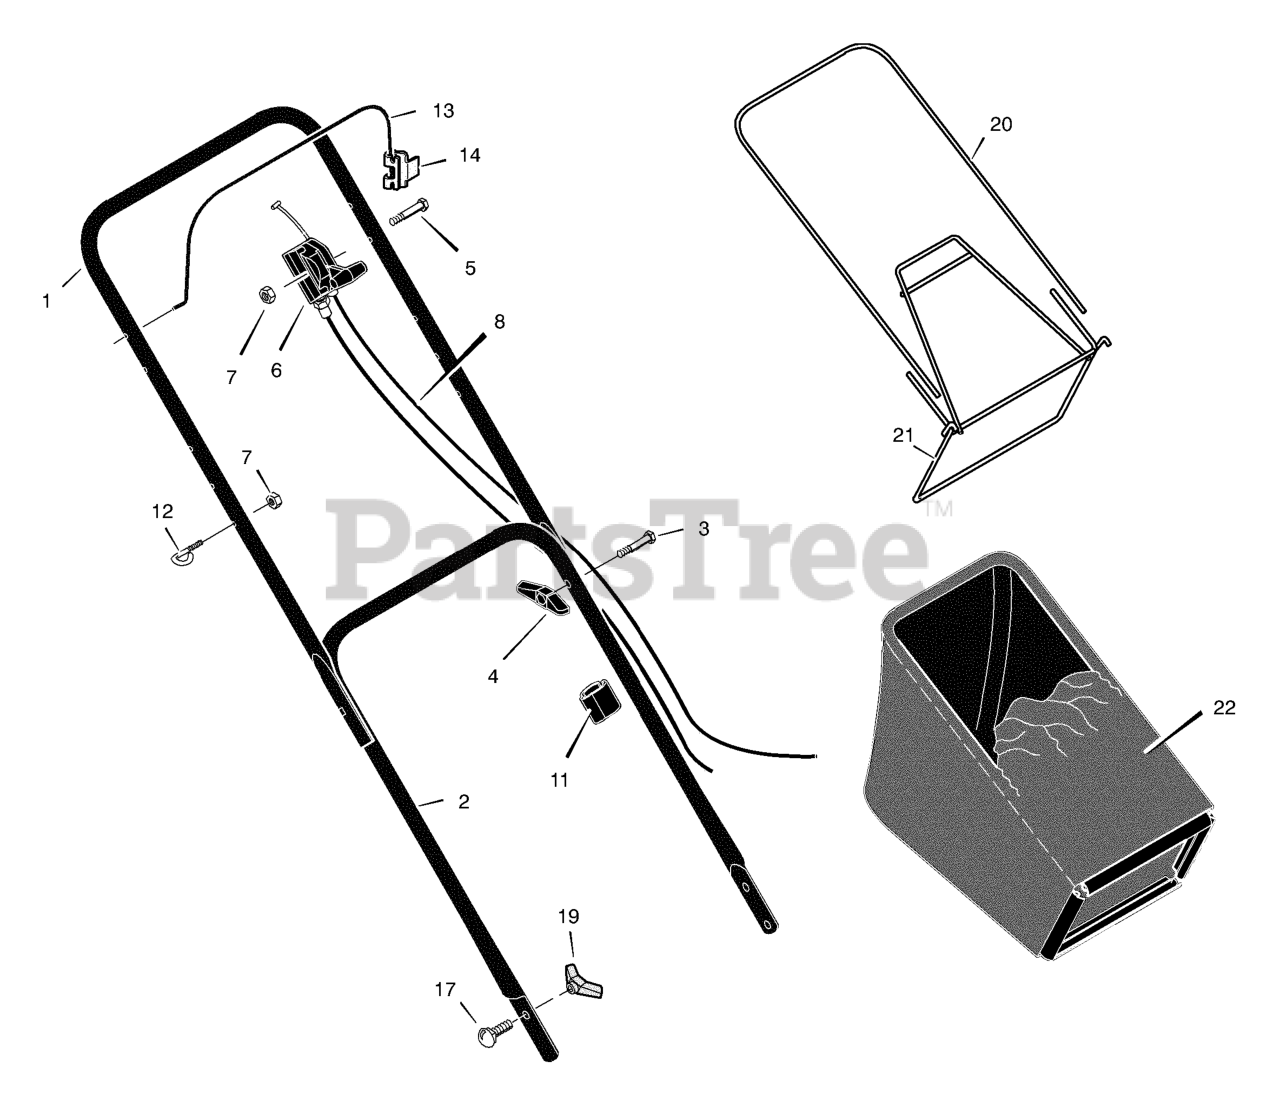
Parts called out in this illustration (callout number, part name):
1	Handle, Upper (Black)
2	Handle, Lower (Black)
4	Knob, Plastic
6	Throttle Control
7	Locknut
8	Engine Stop Cable
11	Clip, Cable
12	Guide, Rope
13	Lever, Engine Stop
14	Bracket, Stop Lever
17	Bolt, Carriage
19	Knob, Plastic
20	Tube, Bag
21	Frame Assembly
22	Bag, Cloth - Grey
